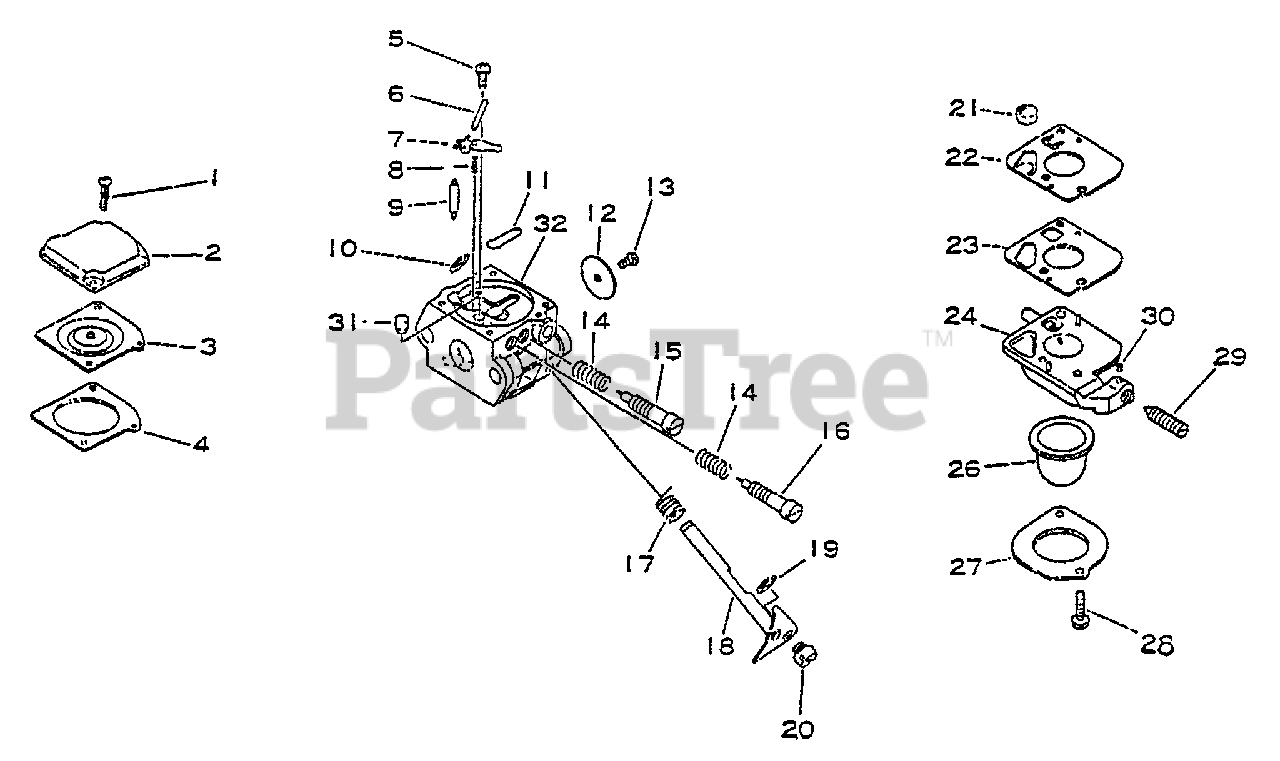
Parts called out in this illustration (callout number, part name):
2	COVER, METERING
3	DIAPHRAGM
4	GASKET, METERING
5	SCREW
6	PIN
7	LEVER, METERING
8	SPRING
9	VALVE, NEEDLE
10	RING, RETAINING
11	PLUG, WELCH
12	VALVE, THROTTLE
15	NEEDLE - HIGH SPEED
16	NEEDLE - LOW SPEED
17	SPRING, RETURN
18	SHAFT, THROTTLE
19	RING, RETAINING
21	STRAINER
22	DIAPHRAGM, PURGE
23	GASKET, PURGE
24	BASE, PURGE
25	BULB, PURGE
26	RETAINER, PURGE BULB
27	SCREW, RETAINER
28	SCREW, IDLE ADJUST
29	PIECE, FRICTION
30	NOZZLE, CHECK VALVE
31	NOZZLE, CHECK VALVE
32	BODY, CARBURETOR
